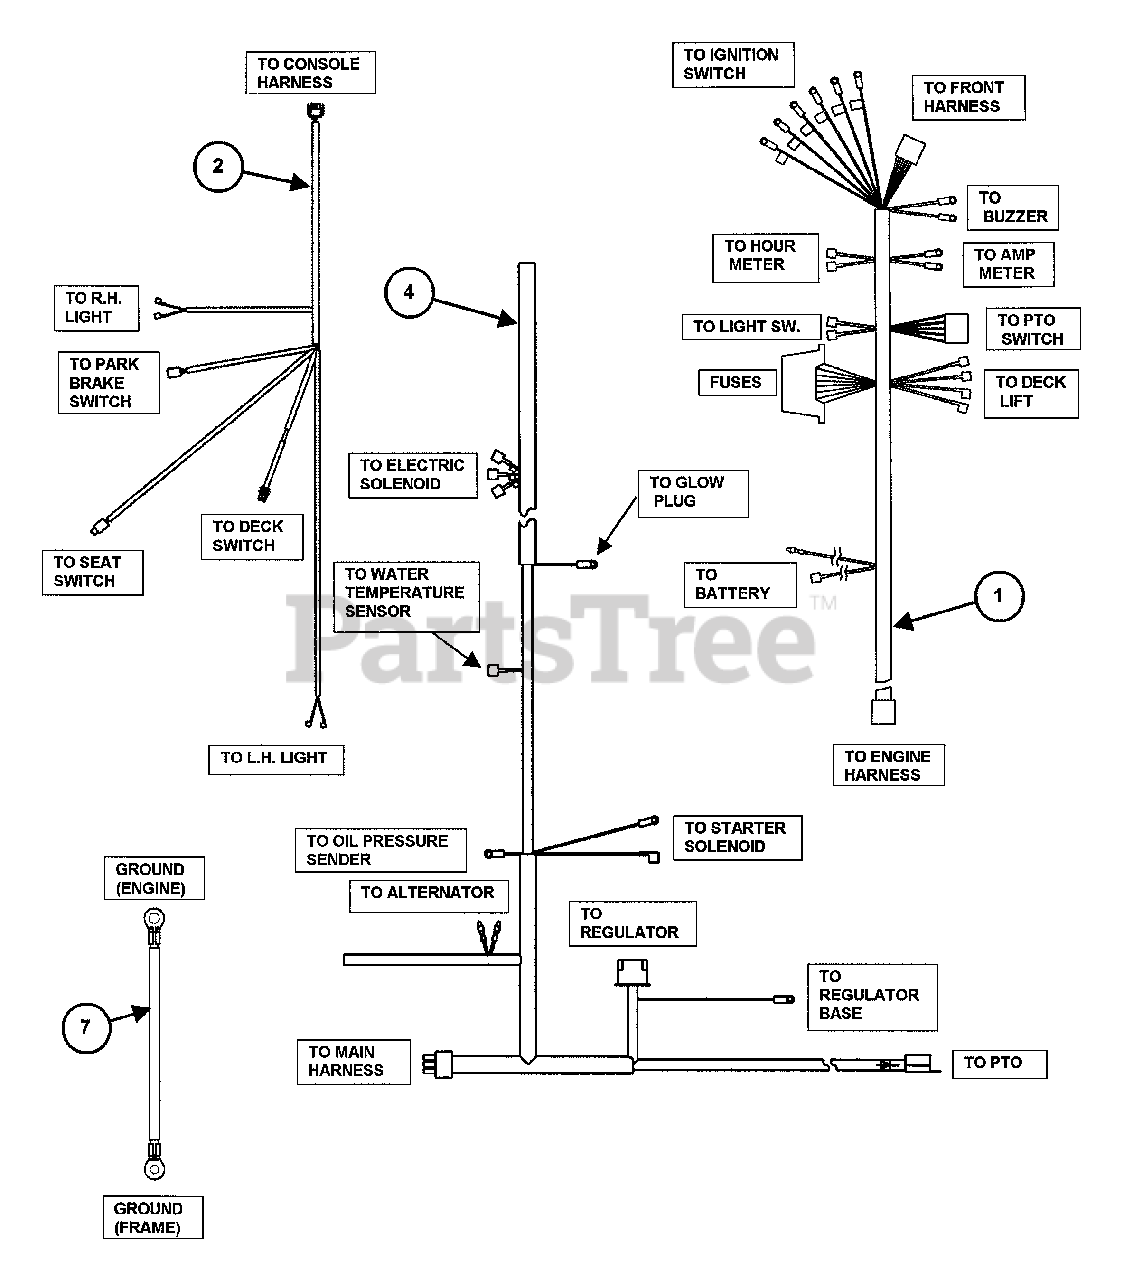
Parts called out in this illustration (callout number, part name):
1	HARNESS, Control Panel
2	HARNESS, Front
4	HARNESS, Engine
7	CABLE, Chassis-Ground (15" Long)
